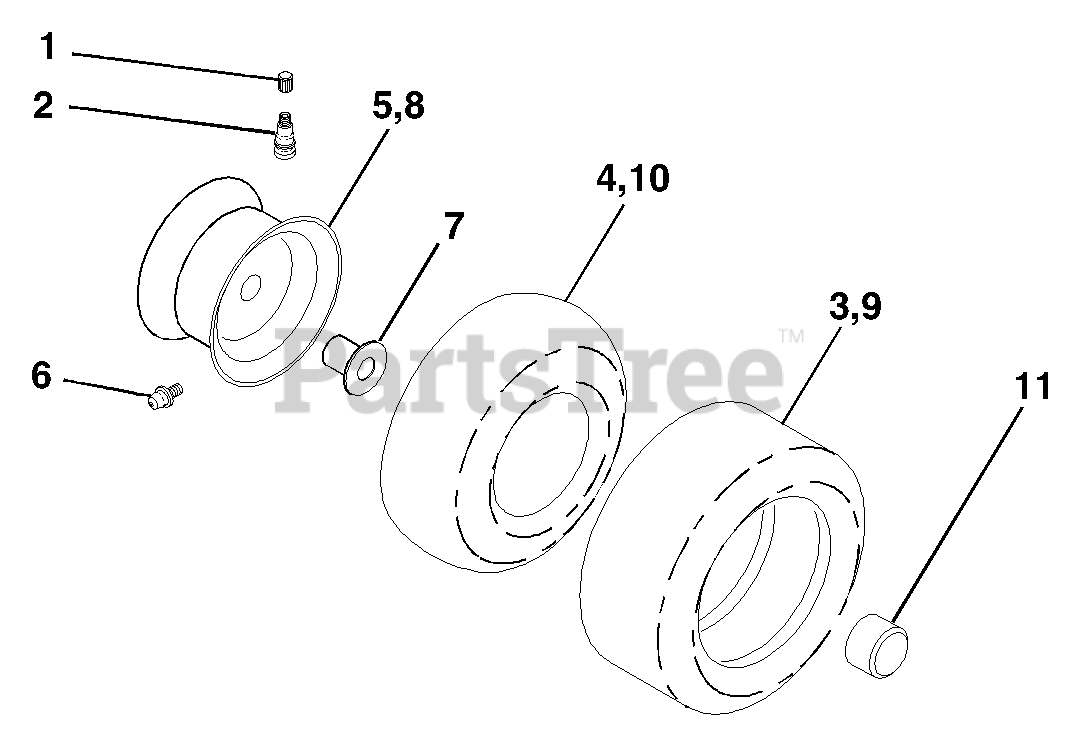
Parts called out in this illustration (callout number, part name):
1	Cap Value Tire
2	Stem Value
3	Tire F Ts 15 X 6 0 - 6 Service
4	Tube Inner Front #35060
5	Rim Asm 6"front White Service
6	Fitting Grease
7	Bearing Flange
8	Rim Asm 8"rear White Service
9	Tire R Ts 18 x 8.5-8 Service
10	Tube Rear 9 5 X 8 Service
11	Cap Axle Blk 1 50 X 1 00
